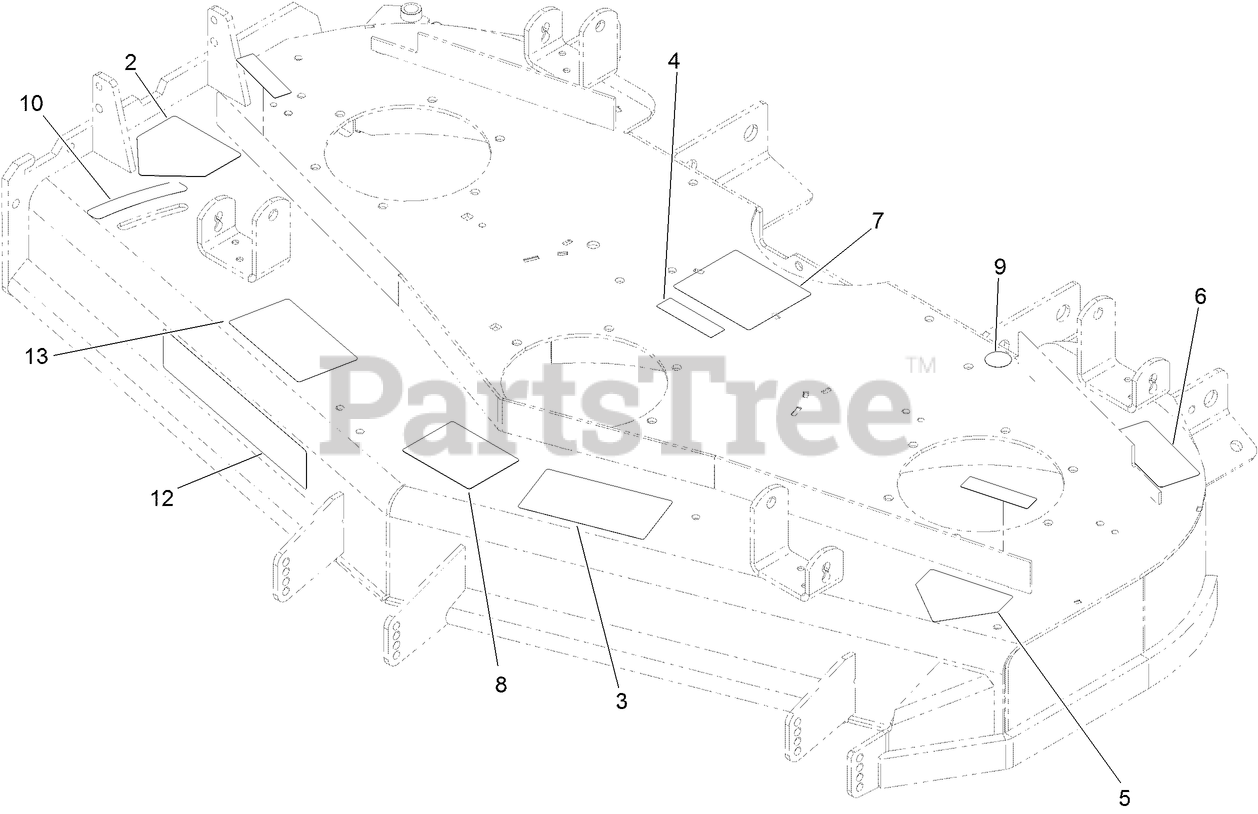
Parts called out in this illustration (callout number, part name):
3	DECAL-DANGER, THROWN OBJECT
4	DECAL-COVER, MISSING
5	DECAL-DANGER
6	DECAL-TORQUE
7	DECAL-ROUTING, BELT
8	DECAL-SCALP, ANTI
9	DECAL-GREASE
10	DECAL-SETTING, BAFFLE
13	DECAL-ADJUSTMENT, BAFFLE
